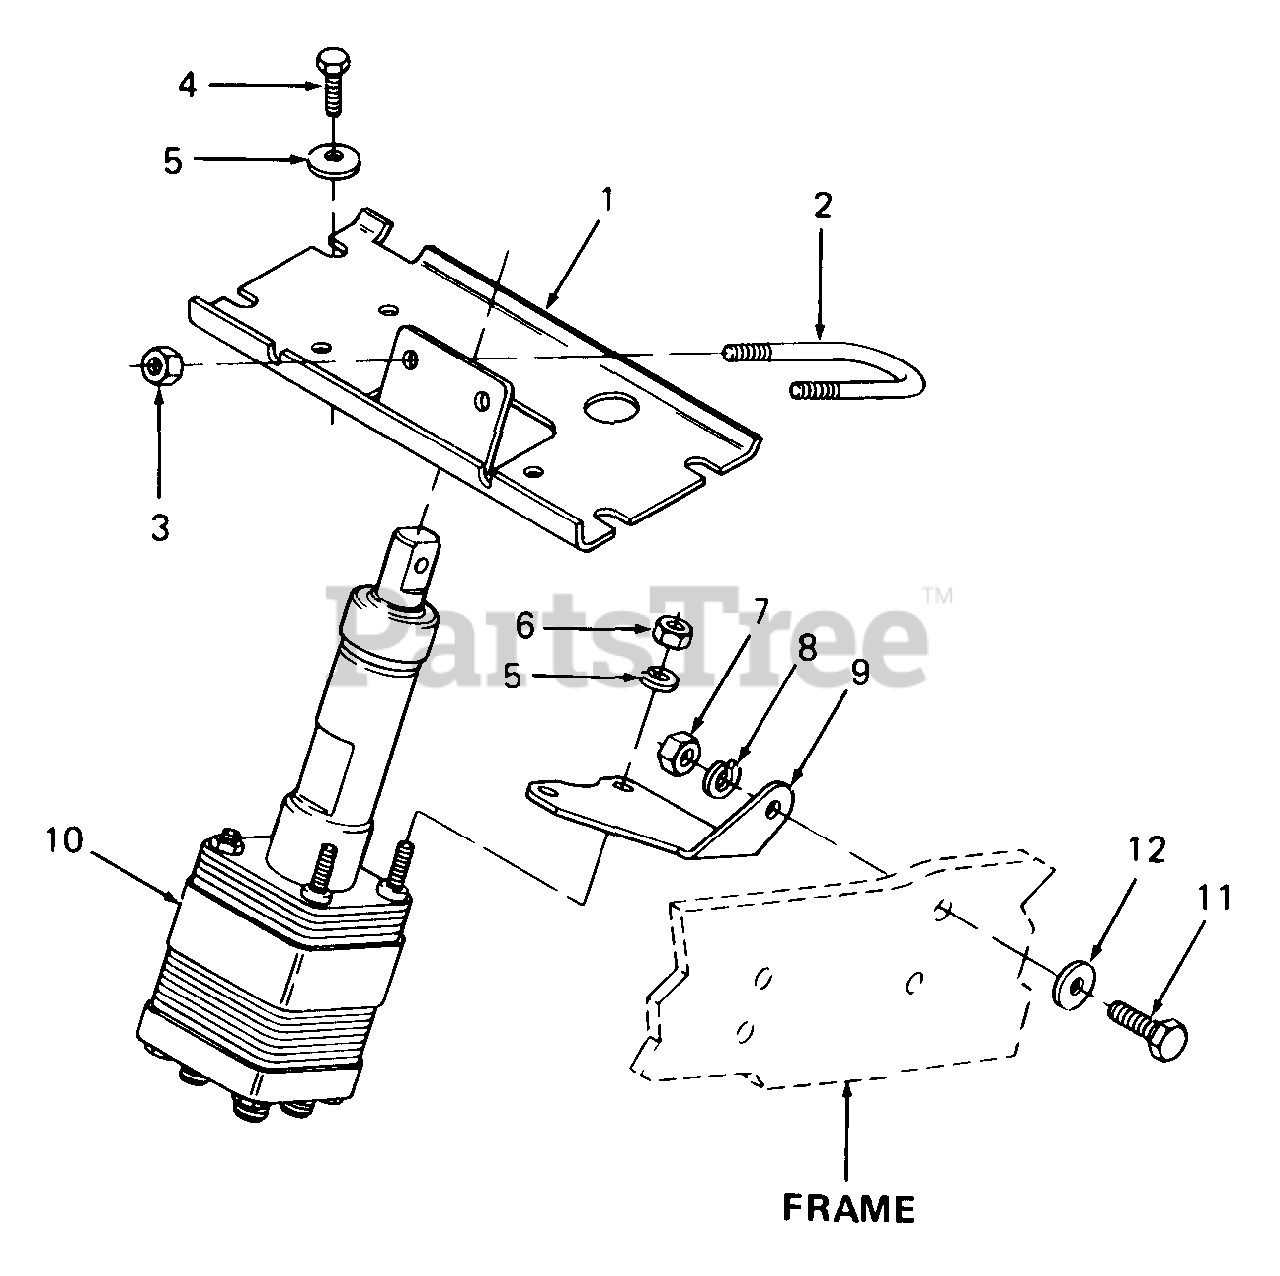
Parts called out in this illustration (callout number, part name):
1	Plate, Steering Support
3	Nut, Hex Center Lock, 5/16-24
4	Screw, Hex Cutting, 5/16-18 x .75 Lg
5	Washer, Bell, .345 x .88 x .060 Thk
6	Nut, Hex, 5/16-24 GR5
7	Nut, Hex Center Lock, 3/8-16 GR5
8	Washer, Lock, 3/8
9	Bracket, Power Steering Box Mtg
10	Power Steering Box w/Flat
11	Screw, Hex Cap, 3/8-16 x .75 Lg GR5
12	Washer, Flat, .385 x .87 x .06 Thk HDN
